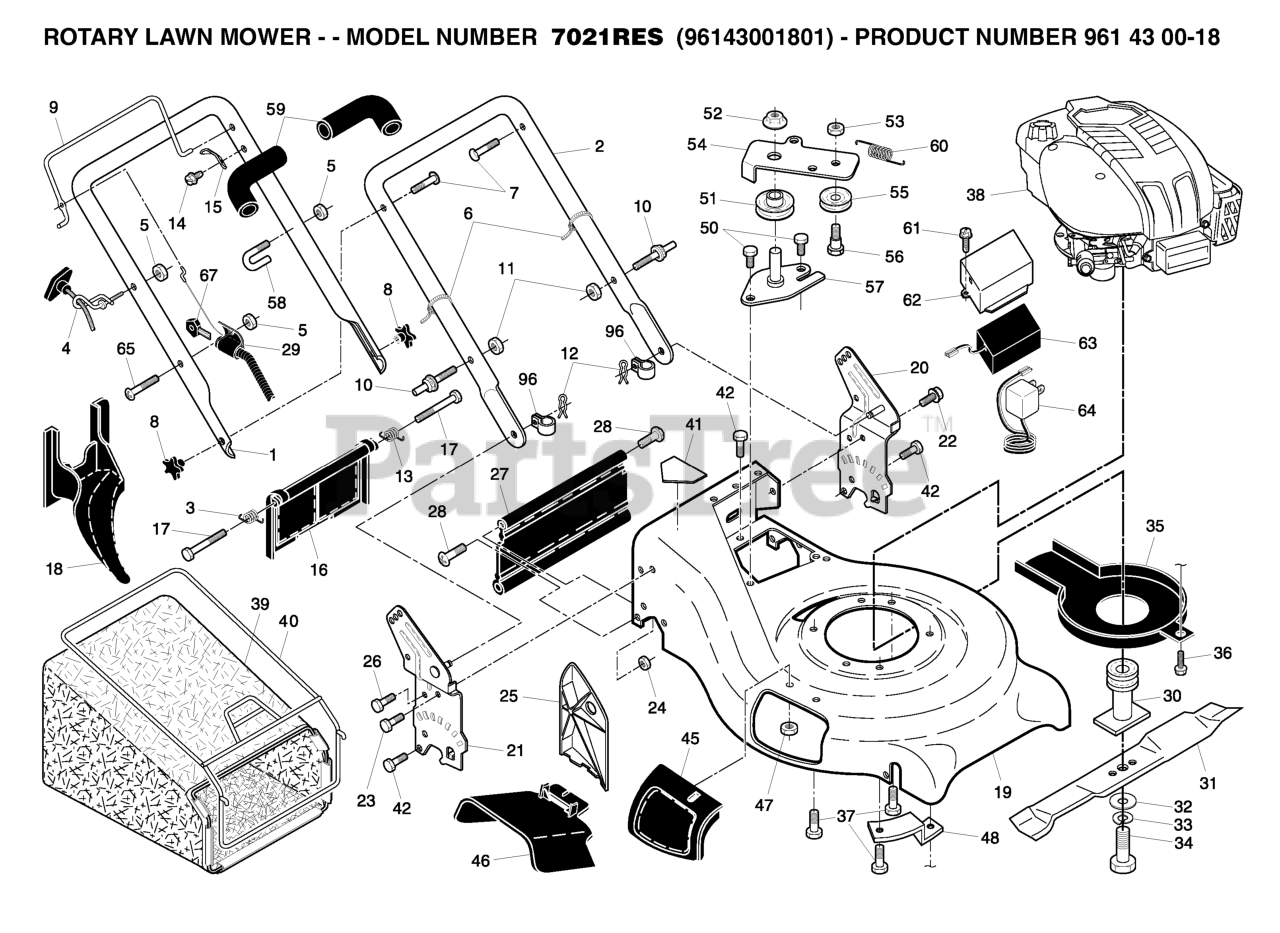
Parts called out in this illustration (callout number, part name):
1	HANDLE.ASM.UP.OFF/EZ.CR.W/GRIP
2	HANDLE.LOWER.21.GREY
3	SPRING.LH.REAR.DOOR.21.RWGD
4	RB GUIDE.ROPE.STD.BLK.ZIN WSL
5	NUT
6	TIE GUIDE
7	BOLT, HANDLE 5/16-18X1.75
8	KNOB.HANDLE.STAR.HUSQ.GRAY
9	BAIL.DSTRT.FL.AW.CREAS.ORANGE
11	NUT.CENTERLOCK.5/16-
12	HAIRPIN COTTER
13	SPRING.RH.REAR.DOOR.21.RWGD
15	BRACKET UPSTOP
16	DOOR.REAR.PLASTIC.21.RWGD.BLAC
18	PLUG.MULCHER.RGD.21.
19	KIT.HSG.21.RGD.4PT.ORA
20	LH HANDLE BRACKET ASSEMBLY
21	BRKT.HANDLE.ASM.RWGD.21.RT.BLA
22	SELF-TAPPING SCREW 5/16-18X3/4
23	BOLT, HEX HEAD 5/16-18
24	NUT.71038.31-18.HEX.NYLOCK
25	CLIPPING DEFLECTOR
27	SKIRT.21.RWGD.BLACK
28	HINGE SCREW
29	CONTROL.COMBI.KEY.ASMR
30	BLADE ADAPTOR / PULLEY
31	BLADE.21.PUSH/RWGD/FWG
32	WASHER,HARDEN
33	LOCKWASHER
34	SCREW, HEX HD 3/8-24 X 1-3/8
35	DEBRIS SHEILD
36	SCREW.HEX.WSH
37	BOLT 3/8-16X1-1/8
39	GBAG.44710247.SILVER.
40	FRAME.CATCHER.21.RGD.AG
41	DECAL HYT
45	MULCHER DOOR ASM.
46	DEFLECTOR, DISCHARGE
48	BRACKET
51	PULLEY.IDLER.V-BELT
52	NUT
53	LOCKNUT
54	ARM.IDLER
55	IDLER PULLEY
56	SHOULDER BOLT
57	BRACKET.IDLER.ASM.EZ
59	GRIP.HANDLE.FOAM.WIDE.(1 SIDE)
60	SPRING, RETURN
61	SCREW.HWH.13-16X1.12
62	BOX.BATTERY.21RD.,RWGD
63	BATTERY WITH AMP CONECTOR AGM
64	RP CHARGER.BATTERY
65	SCREW.(COMBINATION CONTROL)
67	KEY.MOLDED
96	CLIP.CABLE.BLK
